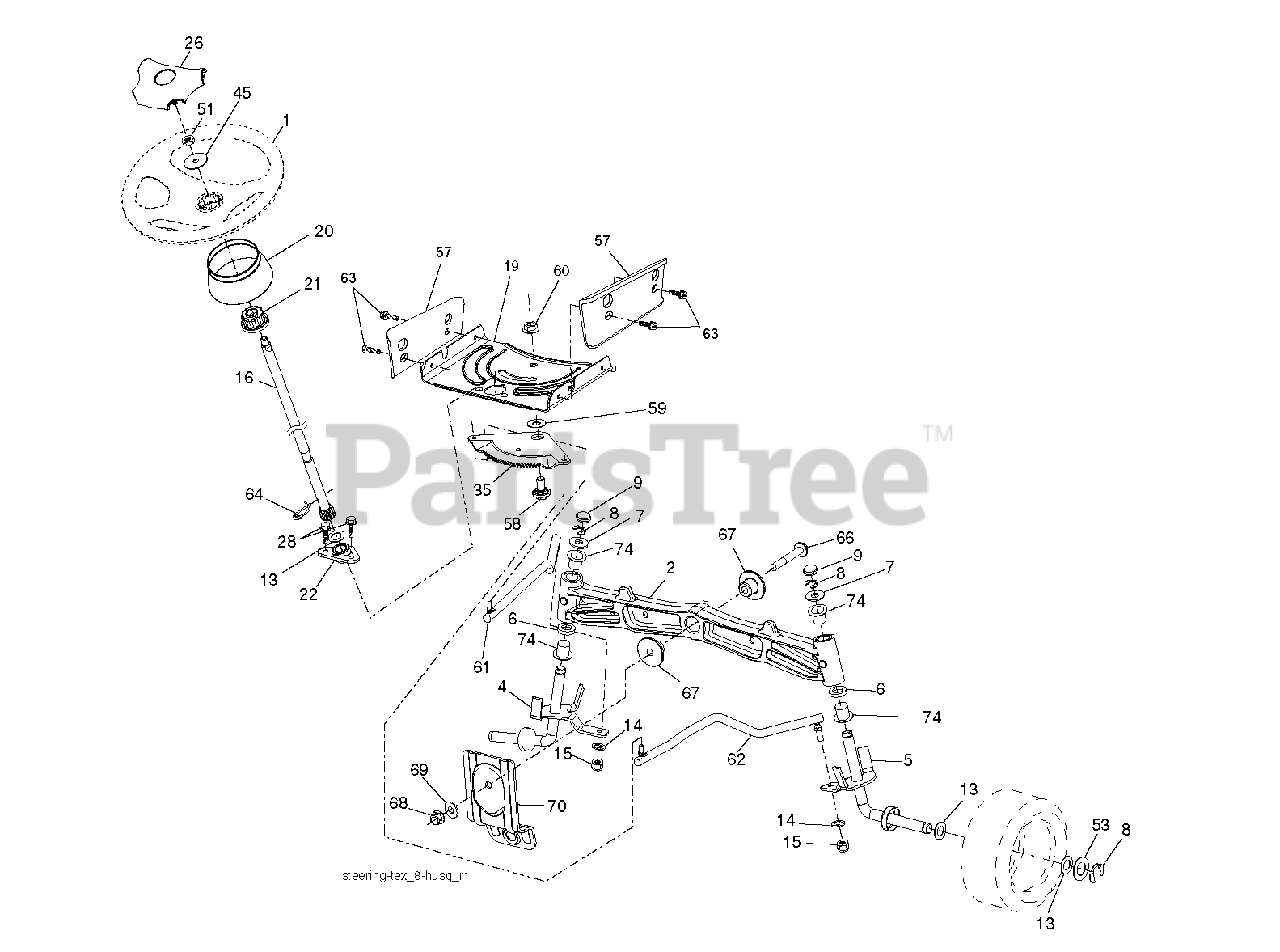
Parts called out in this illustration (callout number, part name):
1	WHEEL.STEERING.STDSRR.BLK/OV
2	AXLE HALF ASM-WELDED
4	SPINDLE.WELDED.LH.15"TEX
5	SPINDLE.WELDED.RH.15"T
8	RING CLIP
9	CAP.SPINDLE
14	WASHER, LOCK 3/8
15	NUT CROWNLOCK 3/8-24
16	SHAFT.STEER.STEALTH.DD
19	PLATE.STEER.DDL.NLT/NG
21	ADAPTER, WHEEL STNG..
22	STEERING.SUPT.LOWER.
26	CAP.WHL.STRNG.STDSRRD.SRS.BLK
28	SCREW, 3/8-16X3/4
35	GEAR.SECTOR.PLATE.DDL.
45	WASHER 9/16"ID, 2 3/8"OD
51	NUT.HEX.1/2-20
53	WASHER.HARDENED
57	BRACKET.UPSTOP.TEX
58	BOLT.SHOULDER.SECTOR.P
59	WASHER.THURST.SECTOR.S
60	NUT FLANGE LOCK 5/8-11
61	DRAGLINK.LH.BALLSTUD.D
62	DRAGLINK.RH.BALLSTUD.D
63	SCREW
64	RETAINER.CLIP.SPRING.S
66	BOLT HEX FGHD 7/16-14 X 3 SERR
67	BUSHING.PM.FRONT AXLE
68	NUT.LOCK.FLANGE.7/16
69	WASHER.1.5X.505X.118
70	BRKT.DECK.SUSPENSION.F
74	BRNG T
